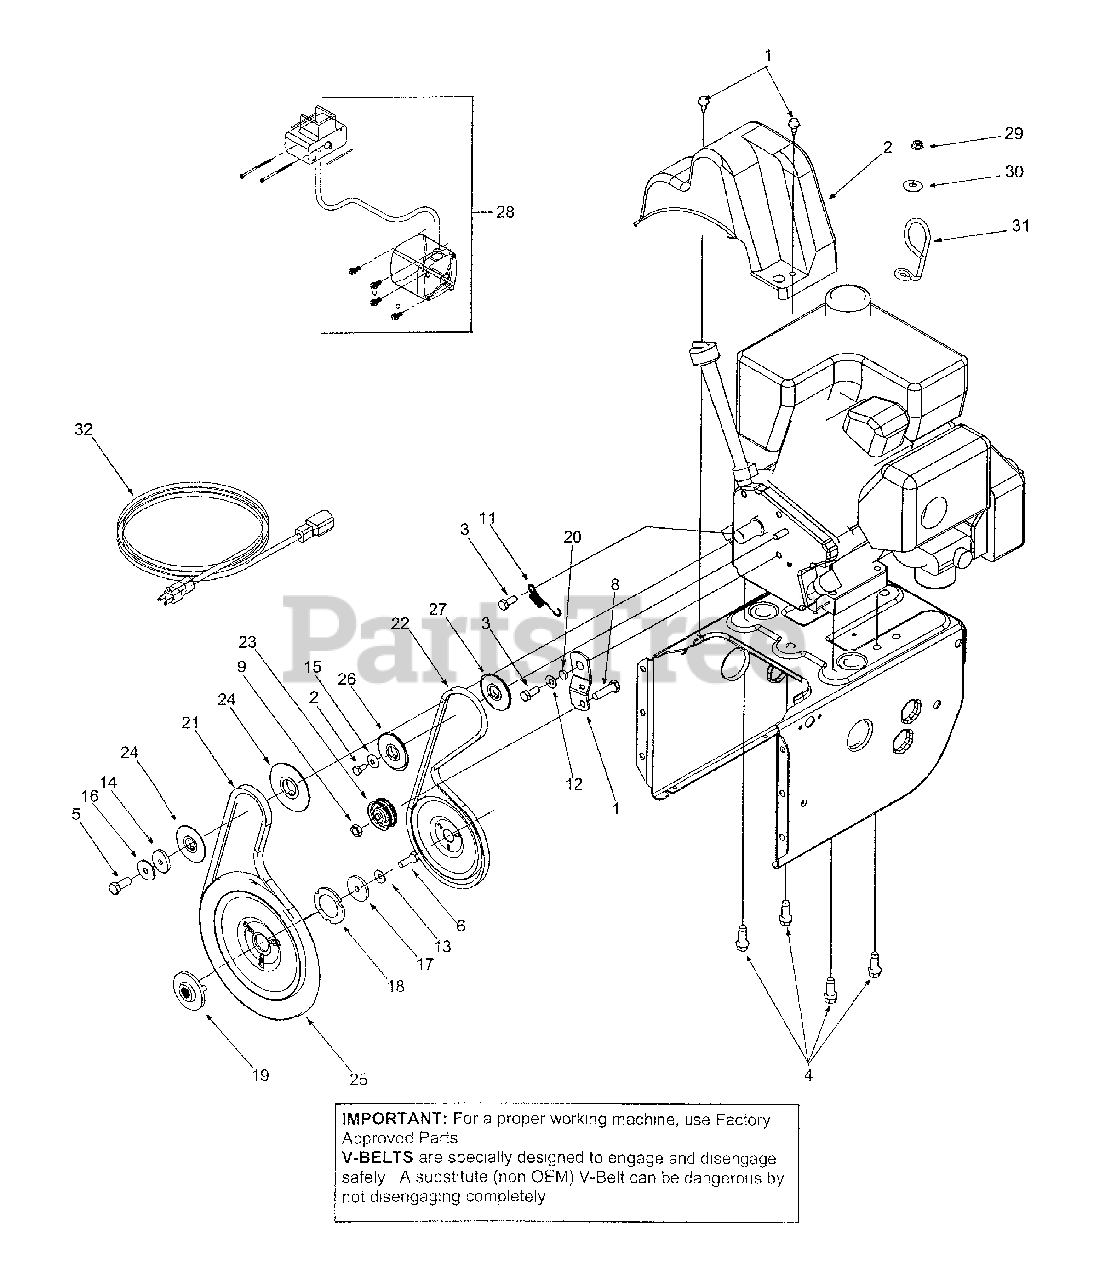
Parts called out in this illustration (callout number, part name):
3	Hex Cap Screw 5/16-24
4	Hex Screw 3/8-16 x 1.0
5	Hex Cap Screw 3/8-24
6	Lock Hex Cap Screw 6/16-24
8	Hex Cap Screw 3/8-16 x 1.25
9	Lock Jam Nut 3/8-16
11	Extension Spring
12	Washer 5/16
13	Bell Washer
14	Flat Washer
15	Bell Washer
16	Bell Washer
17	Flat Washer
18	Special Washer
19	Adapter Pulley
21	Belt
22	V-Belt
23	Flat Idler
24	Pulley Half
25	Auger Pulley
26	Pulley Half
27	Pulley Half
28	Electric Start Kit
29	Lock Nut, 1/4-20
30	Flat Washer, .28 x .74 x .063
31	Cable Guide
32	Extension Cord
